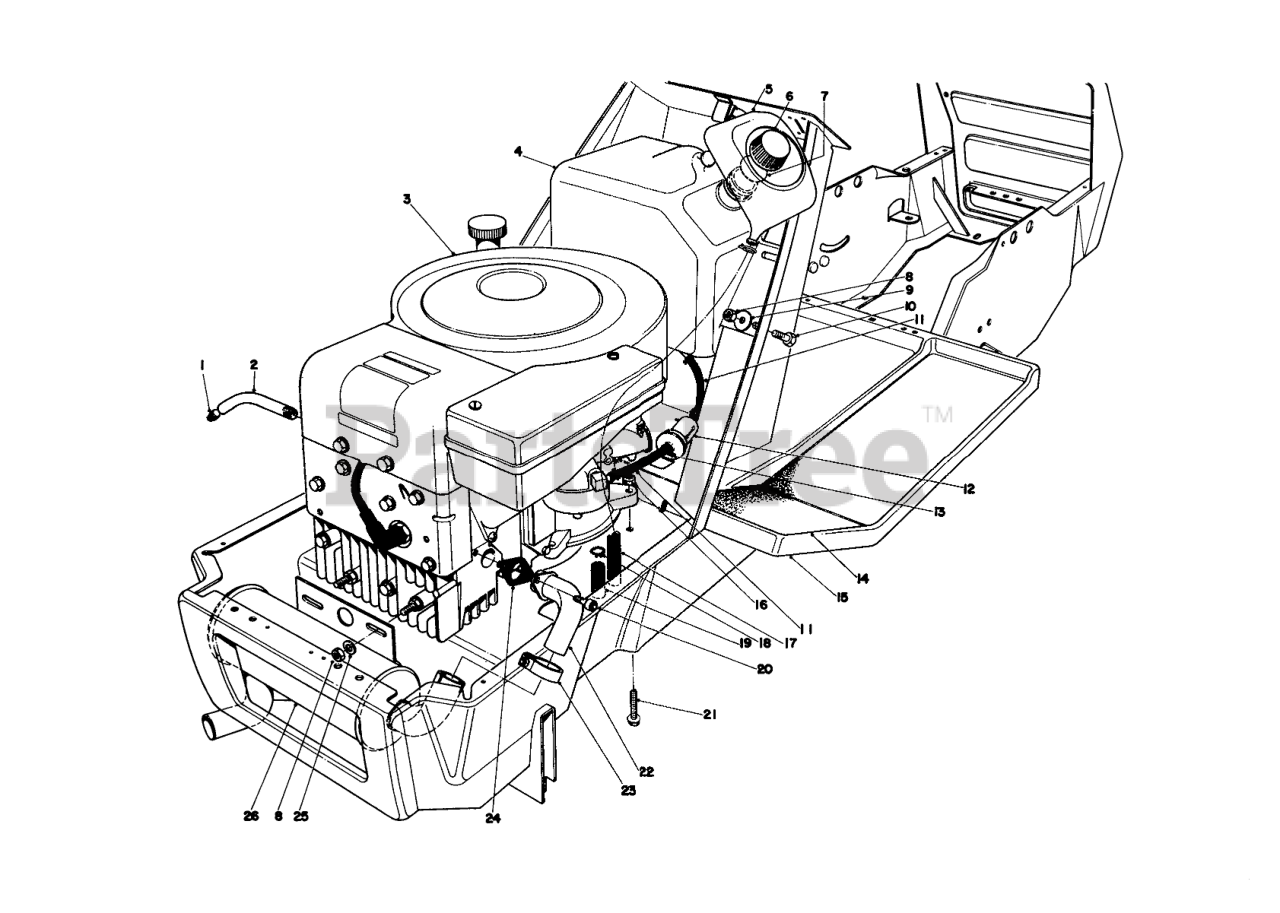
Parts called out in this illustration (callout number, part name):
1	PLUG-PIPE, SQH
2	OIL DRAIN TUBE
3	Engine
4	Gas Tank (Incl. Ref. #5)
5	Funnel-Overflow
6	Gas Cap (Incl. Ref. #7)
7	Gasket Gas Cap
8	NUT-LOCK, CONE
9	WASHER
10	SCREW-HH
11	GAS HOSE
12	FUEL FILTER
13	Clamp
14	LH FOOT TREAD
15	Frame
16	NUT-LOCK, CONE
17	Hose Funnel
18	HOSE CLAMP
19	Hose Carburetor Drain
20	SCREW-HSH
21	SCREW-HH
22	Exhaust Pipe
23	Clamp-Exhaust Pipe
24	Exhaust Gasket
25	WASHER-PLAIN
26	MUFFLER
